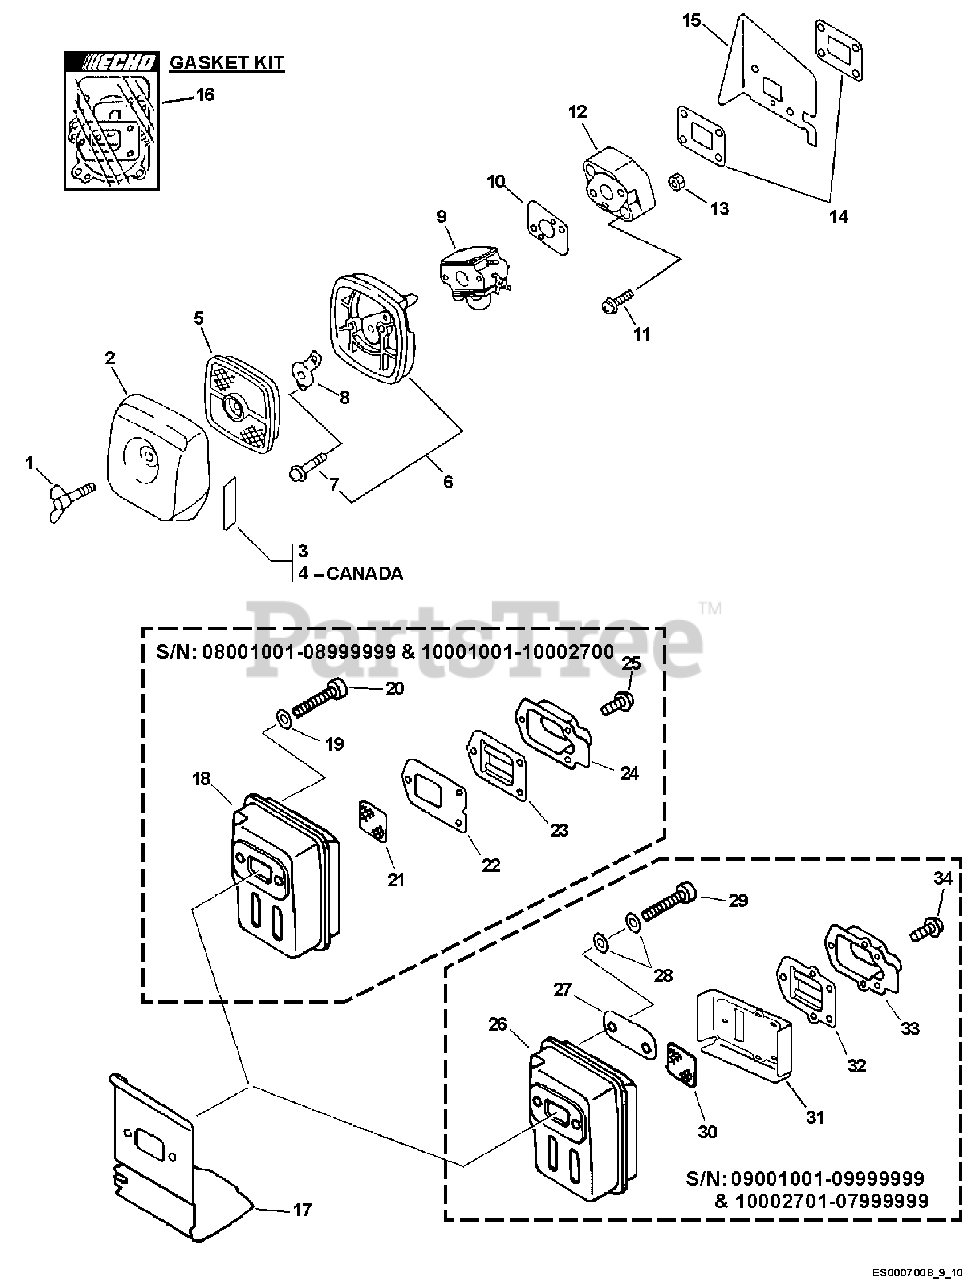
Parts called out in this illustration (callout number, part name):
1	THUMBSCREW
2	COVER, AIR FILTER - GRAY
3	LABEL - CHOKE
4	LABEL - CHOKE
5	FILTER, AIR - SINGLE LAYER
6	AIR FILTER CASE ASSY
7	SCREW - 5X65
8	PLATE, PREVENT
9	CARBURETOR
10	GASKET, INTAKE
11	SCREW - 5X22
12	INSULATOR, INTAKE
14	GASKET, INTAKE
15	SHIELD, INTAKE
16	GASKET KIT
17	SHIELD, EXHAUST
19	WASHER - 5
20	SCREW - 5X55
21	SCREEN, SPARK ARRESTOR
22	GASKET, EXHAUST
23	GUIDE, EXHAUST - INNER
24	GUIDE, EXHAUST - OUTER
25	SCREW - 4X10
26	MUFFLER
28	WASHER - CONICAL
29	SCREW - 5X55
30	SCREEN, SPARK ARRESTOR
31	GASKET, EXHAUST
32	GUIDE, EXHAUST - INNER
33	GUIDE, EXHAUST - OUTER
34	SCREW - 4X12
